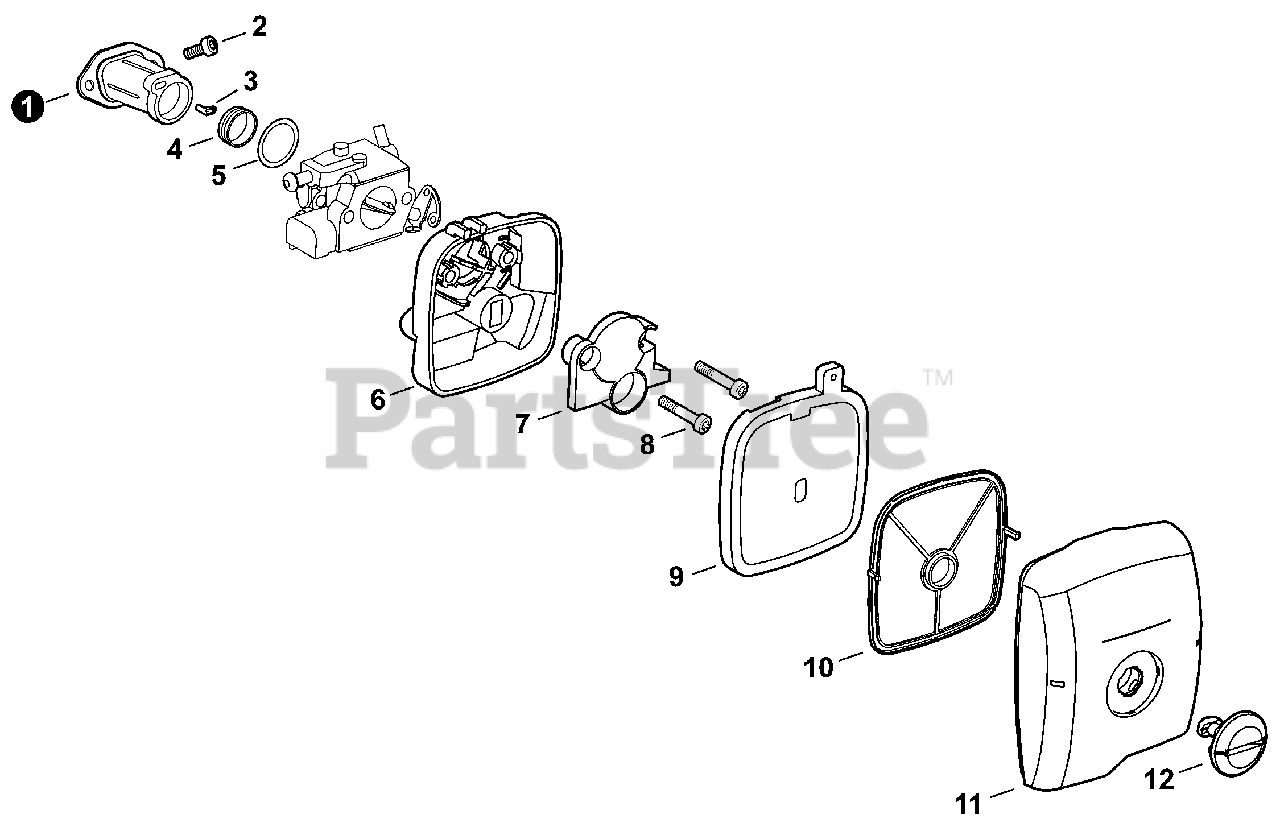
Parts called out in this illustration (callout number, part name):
1	BELLOWS, INTAKE
2	BOLT, TORX 5×12
3	COLLAR Ø3.2×6.5
4	SPRING, TENSION
6	CASE, AIR FILTER
7	PLATE, PREVENT
8	BOLT, TORX 5×50
9	FILTER, AIR
10	SEAL, AIR FILTER
11	COVER, AIR FILTER
12	KNOB, AIR FILTER COVER
